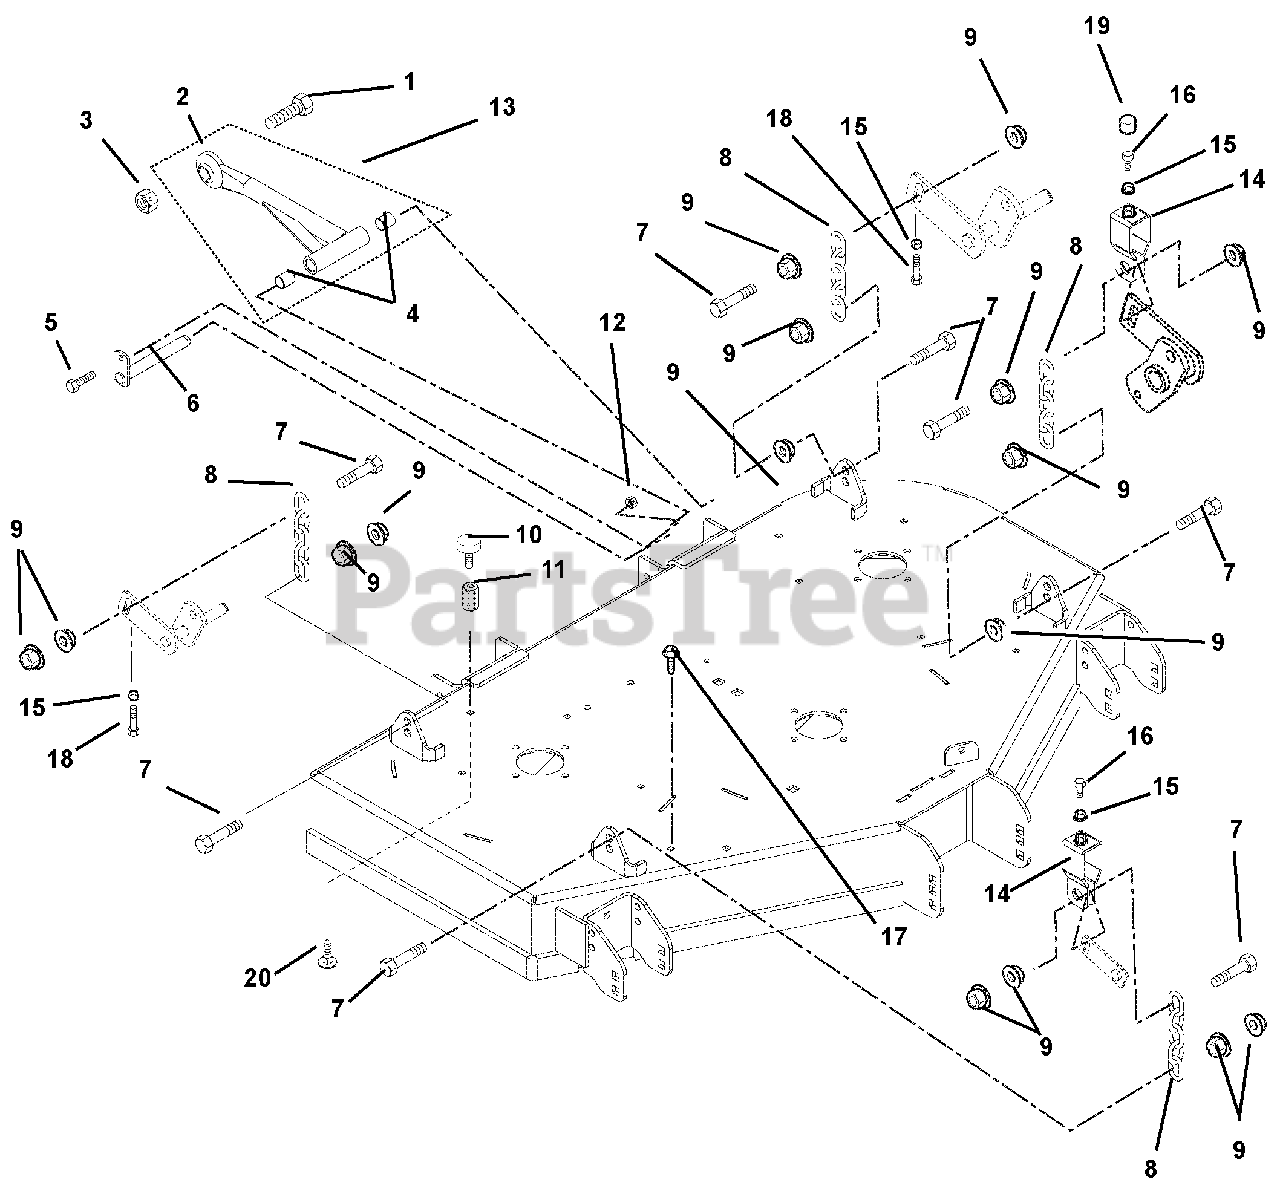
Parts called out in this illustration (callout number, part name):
1	BLT-HEX .875-9X2.75 GR5 YWZC
2	MOWER MOUNTING ARM WMT - BLACK
3	NUT-LK-CTR .875-9 YWZC
4	BRG, .750 X .875 X 1.000
5	@BLT-HEX .38-16X.75 GR5 YWZC
6	WELDMENT, MOWER MTG. PIN
7	BLT, HEX M12-1.75X50 CLS8.8 YZ
8	CHAIN, LINK
9	NUT-SPNLK-FLG M12-1.75 YZ
10	BUMPER, RUBBER
11	NUT, COUPLING .31-18 X 3.00
12	@NUT-LK-NYL-FLG .38-16 YWZC
13	ASSM, MOWER MOUNTING ARM
14	BRKT, DECK LEVELING
15	NUT- JAM .312-18 YWZC
16	BLT-HEX .312-18X2.00 FTH GR5YZ
17	@SCR-TAP .38-16X.50 HWH TR YWZ
18	BLT-HEX .312-18X1.50 FTH GR5YZ
19	CAP-VINYL .50ID X 1.50LG X.055
20	BLT,RDHDSQNK .31-18X.75 LOCTIT
